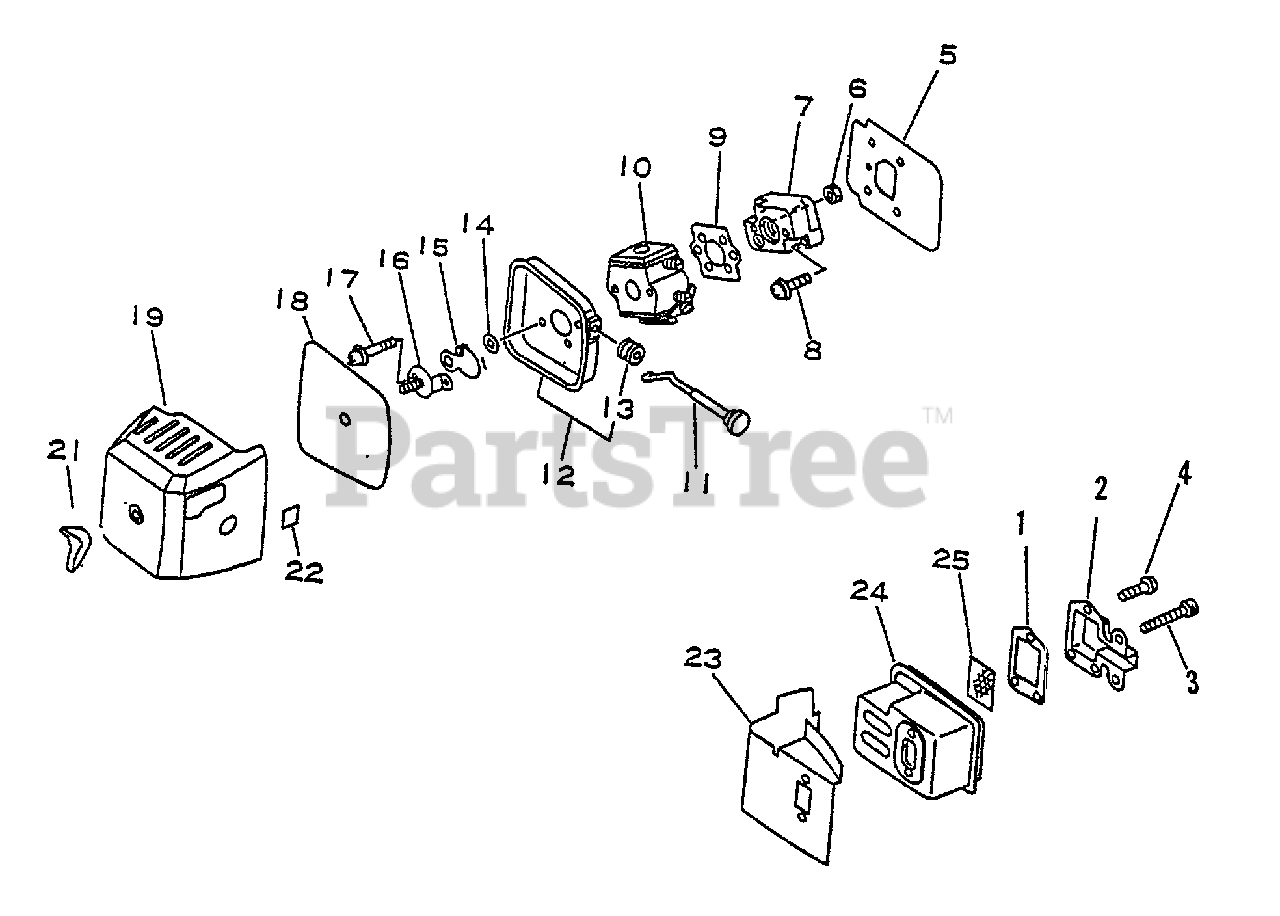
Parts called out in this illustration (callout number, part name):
1	GASKET, EXHAUST
2	GUIDE, EXHAUST
3	BOLT M5×50
4	SCREW 4×10
5	GASKET, INTAKE
6	NUT M5
7	INSULATOR, INTAKE
8	SCREW 5×20
9	GASKET, INTAKE
10	CARBURETOR
11	ROD, CHOKE
12	CASE, AIR FILTER
13	GROMMET, CHOKE
14	WASHER 5.2×8×0.8T
15	SHUTTER, CHOKE
16	PLATE, PREVENT
17	SCREW 5×57
18	FILTER, AIR
19	COVER, AIR FILTER
21	WINGNUT - 5
22	LABEL, CHOKE
23	COVER, MUFFLER
25	SCREEN, SPARK ARRESTER
